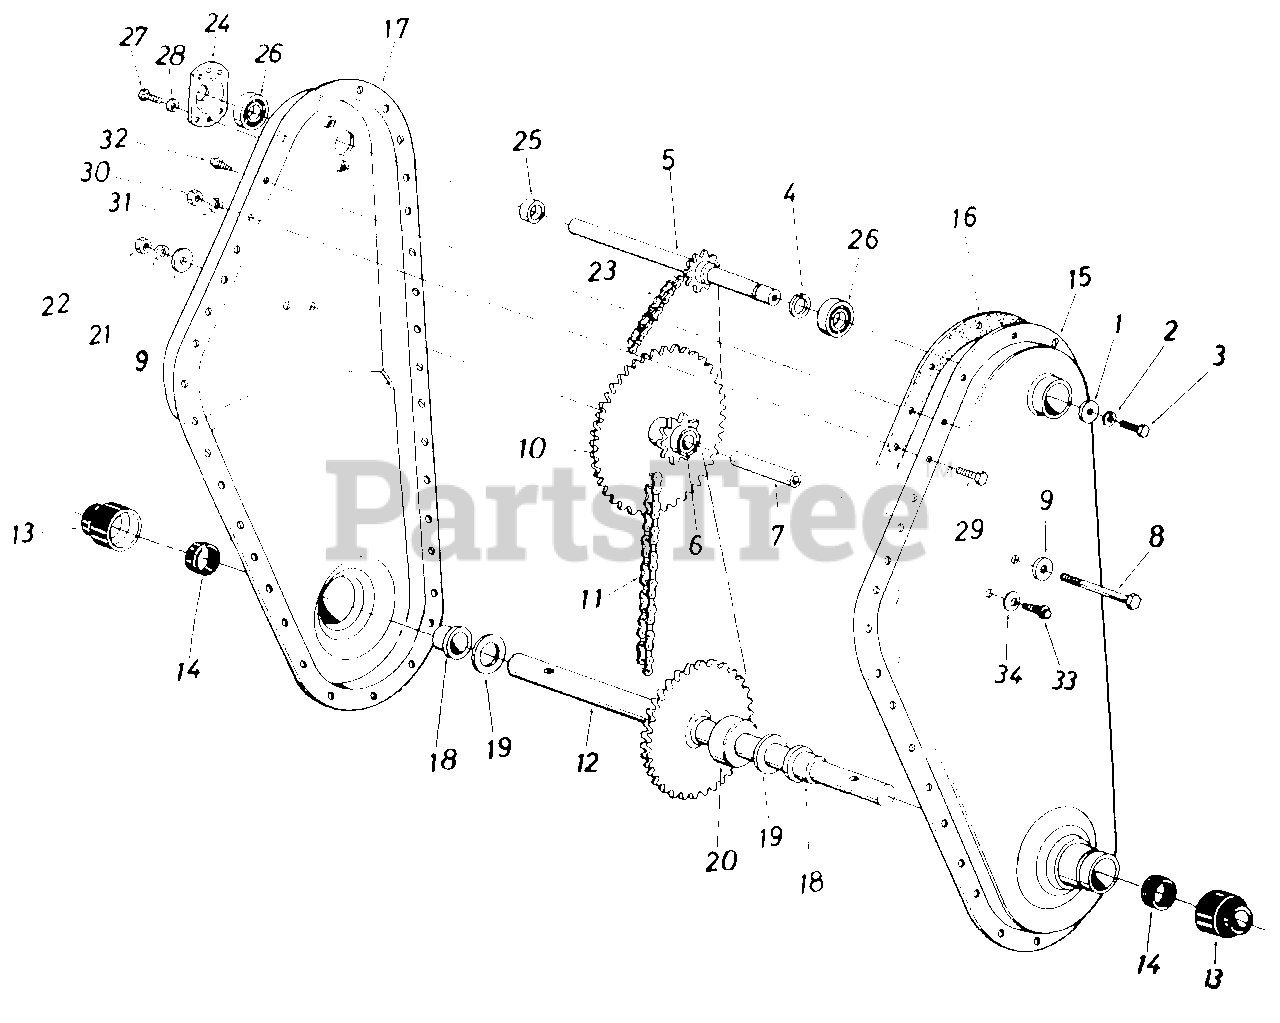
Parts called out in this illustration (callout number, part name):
1	Fl-Wash. 1/4" I.D. x .93" O.D. x .1.20
2	L-Wash. 1/4" I.D.
3	Hex Bolt 1/4-28 x .62" Lg. w/ Patch
4	External Snap Ring-5/8" Dia.
5	Input Shaft Ass'y.
6	Bearing 5/8" I.D. x 3/4" O.D. x 1.860" Lg .
7	Sprocket Hub Tubing 3/8" I.D. x 5/8" O.D. x 1.90
8	Hex Bolt 3/8-24 x 2.75" Lg.
9	Fl-Wash. 3/8" I.D. x 1.25" O.D. x .10
10	Sprocket Ass'y.
11	#50 Chain 5/8" Pitch x 46 Links Endless
12	Tine Shaft Ass'y.
13	Dust Cup
14	Seal Ring Single Lip, Springless
19	Fl-Thrust Wash. 1.0" I.D. x .03 Thk.
20	Step Spacer
21	L-Wash. 3/8" I.D.
22	Hex Nut 3/8-24 Thd.
23	#35 Chain 3/8" Pitch x 52 Links Endless
24	Bearing Housing 1.38" I.D.
25	Spacer
26	Ball Bearing .625" I.D. x 1.38" O.D. x .437
27	Hex Wash. SF-Tap Scr. 1/4-20 x .50" Lg.
28	L-Wash. 1/4" I.D.
29	Hex Bolt 5/16-18 x .75" Lg.*
30	Hex Nut 5/16-18 Thd.
31	L-Wash. 5/16" I.D.
32	Hex Wash. SF-Tap Scr. 1/4-20 x .50" Lg.
33	Hex Wash. Hd. Tap Scr. 1/4-20 x .38" Lg.
34	Bell-Wash. .265" I.D. x .75" O.D.
